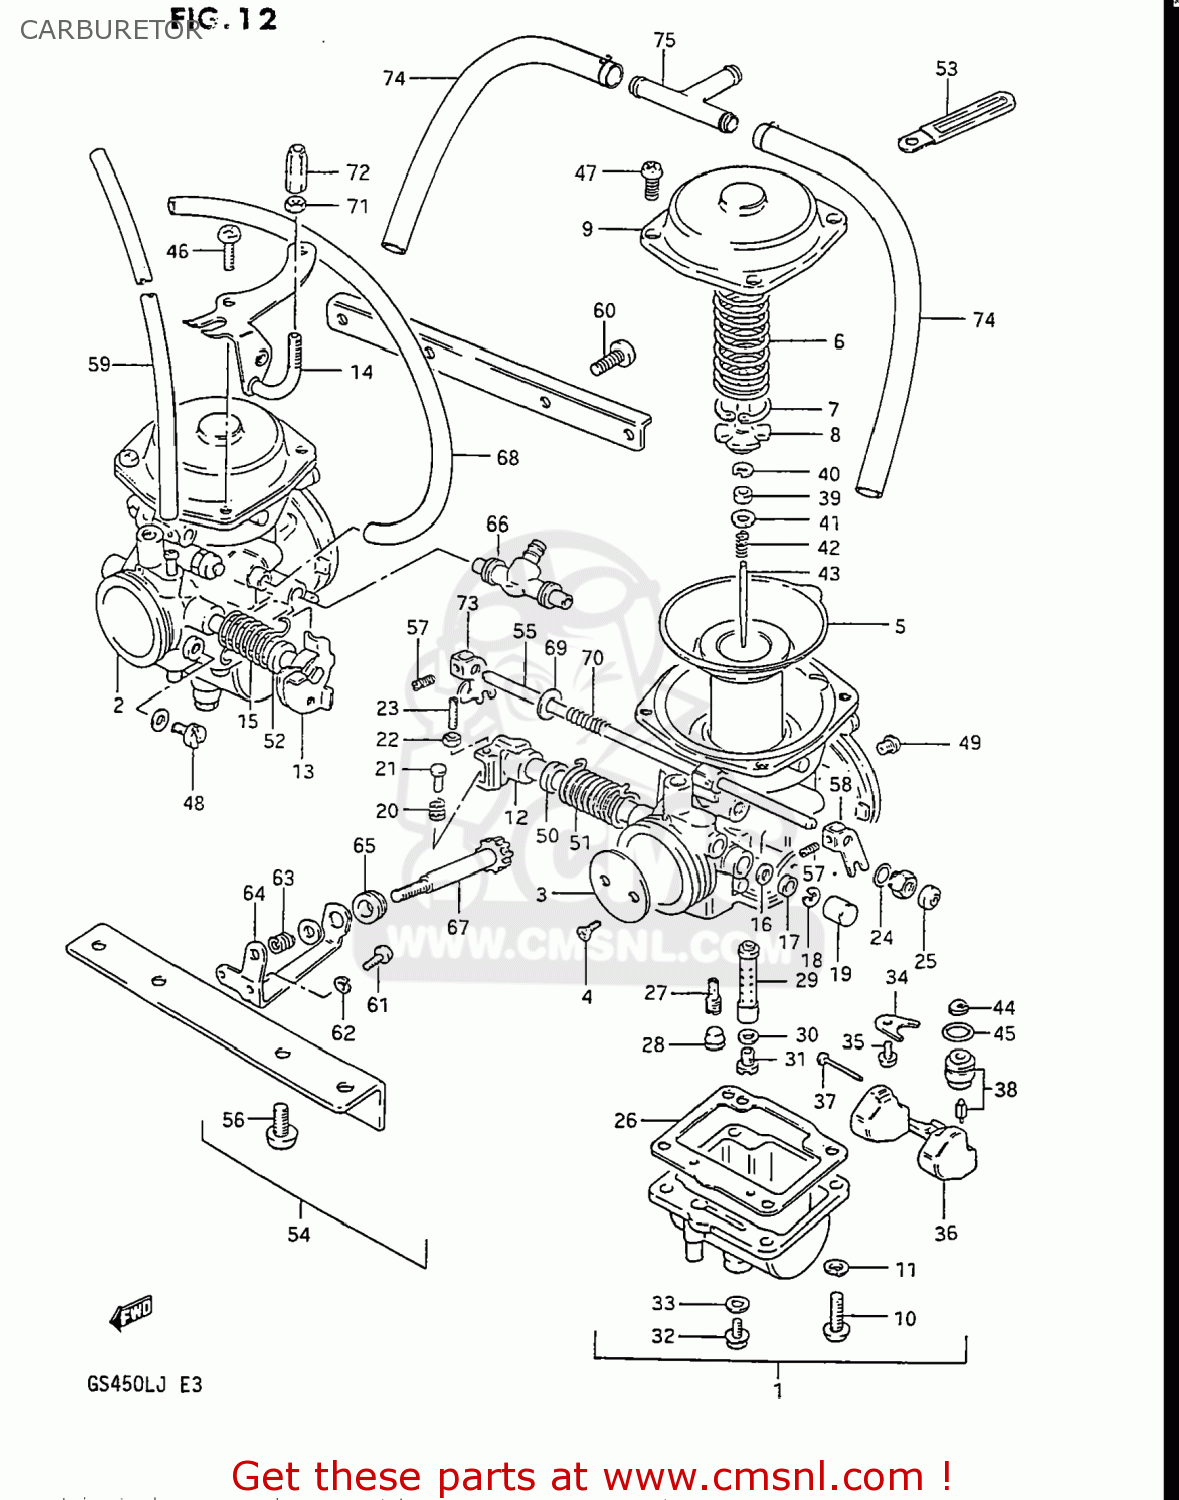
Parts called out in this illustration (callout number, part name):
1	CARBURETOR
2	CARBURETOR ASSEMBLY
3	VALVE,THROTTLE
4	SCREW
5	DIAPHRAGM ASSY
6	SPRING
7	E RING
8	HOLDER,GUIDE
9	COVER
10	SCREW
11	LOCK WASHER
12	SHAFT ASSEMBLY
13	SHAFT,THROTTLE
14	BRACKET,THROTTLE CABLE
15	SPRING
16	SEAL
17	GASKET,THROTTLE SHAFT (NAS)
18	E RING
19	CAP
20	SPRING,THROTTLE SCREW
21	PIN,THROTTLE LEVER
22	NUT
23	SCREW
24	O RING
25	CAP,STARTER VALVE
26	GASKET,FLOAT CHAMBER (NAS)
27	JET,PILOT(45)
28	PLUG,NEEDLE JET
29	JET,NEEDLE
30	WASHER,NEEDLE NOZZLE
31	JET,MAIN(115)
32	PLUG,DRAIN
33	GASKET (NAS)
34	PLATE,NEEDLE VALVE FITING
35	SCREW
36	FLOAT
37	PIN,FLOAT
38	VALVE ASSEMBLY,NEEDLE
39	RING
40	CLIP
41	PIN,FLOAT
42	SPRING
43	NEEDLE JET
44	FILTER
45	O-RING,NEEDLE VALVE
46	SCREW 5X10
47	SCREW
48	SCREW
49	JET,AIR
50	SPACER,THROTTLE SHAFT
51	SPRING
52	SPACER,THROTTLE SHAFT
53	CLAMP L:35
54	FLANGE ASSEMBLY,CARBURETOR
55	SHAFT,STARTER
56	SCREW
57	SCREW
58	LEVER
59	HOSE 4.5X8X600
60	SCREW 5X12
61	SCREW
62	LOCK WASHER
63	SPRING,THROTTLE ADJUST
64	BRACKET,THROTTLE ADJUST
65	BUSHING,THROTTLE ADJUSTER
66	NIPPLE,CARBURETOR
67	SCREW
68	HOSE
69	WASHER,STARTER PLUNGER
70	SPRING,STARTER
71	NUT
72	ADJUSTER
73	LEVER,STARTER
74	HOSE
75	JOINT,3 WAY
